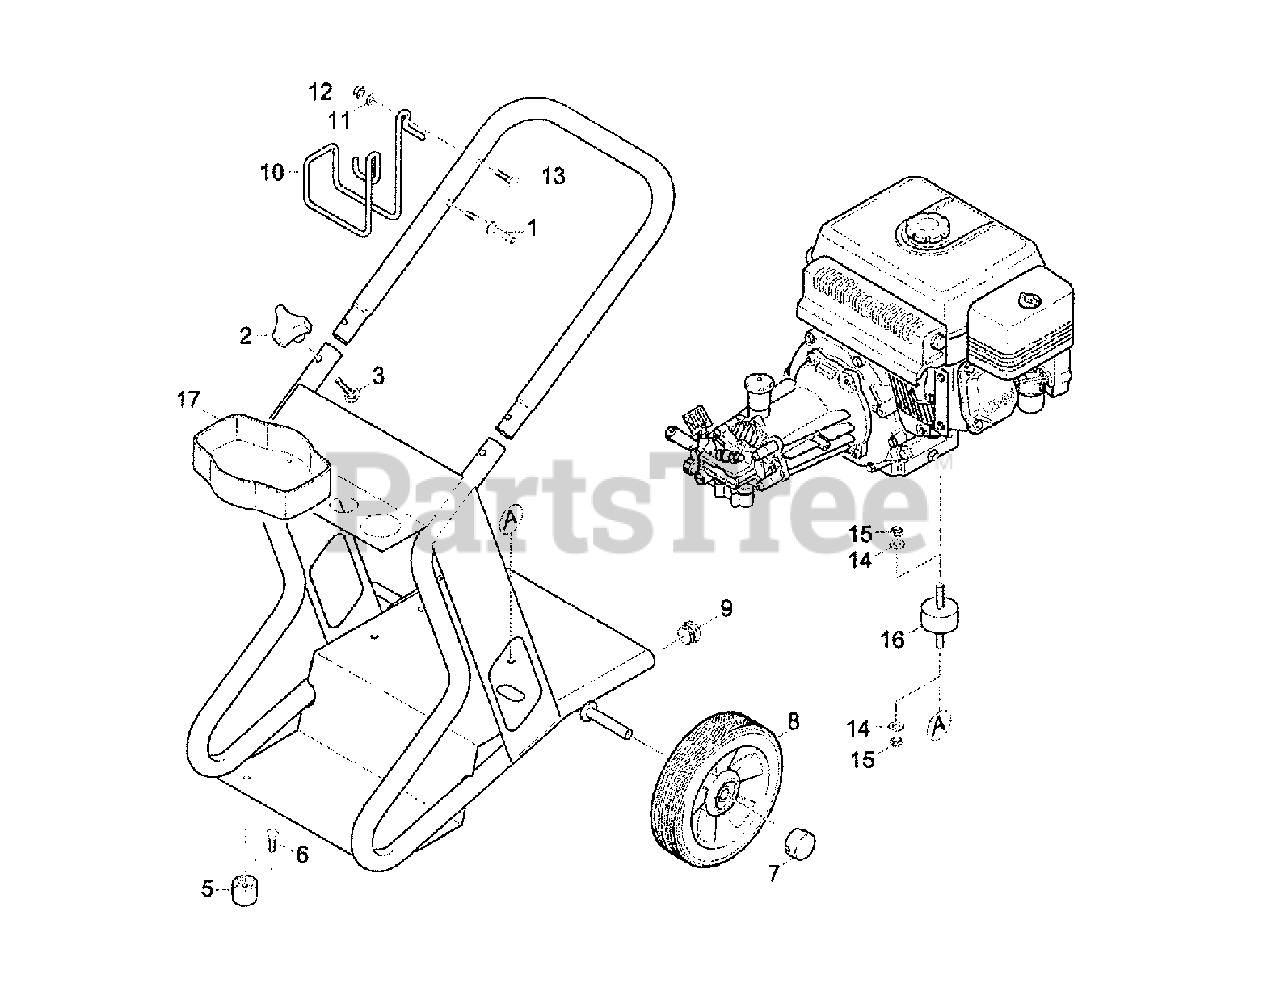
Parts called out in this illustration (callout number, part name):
2	Control Knob
5	Rubber Bumper
17	Tray, 1 gal
